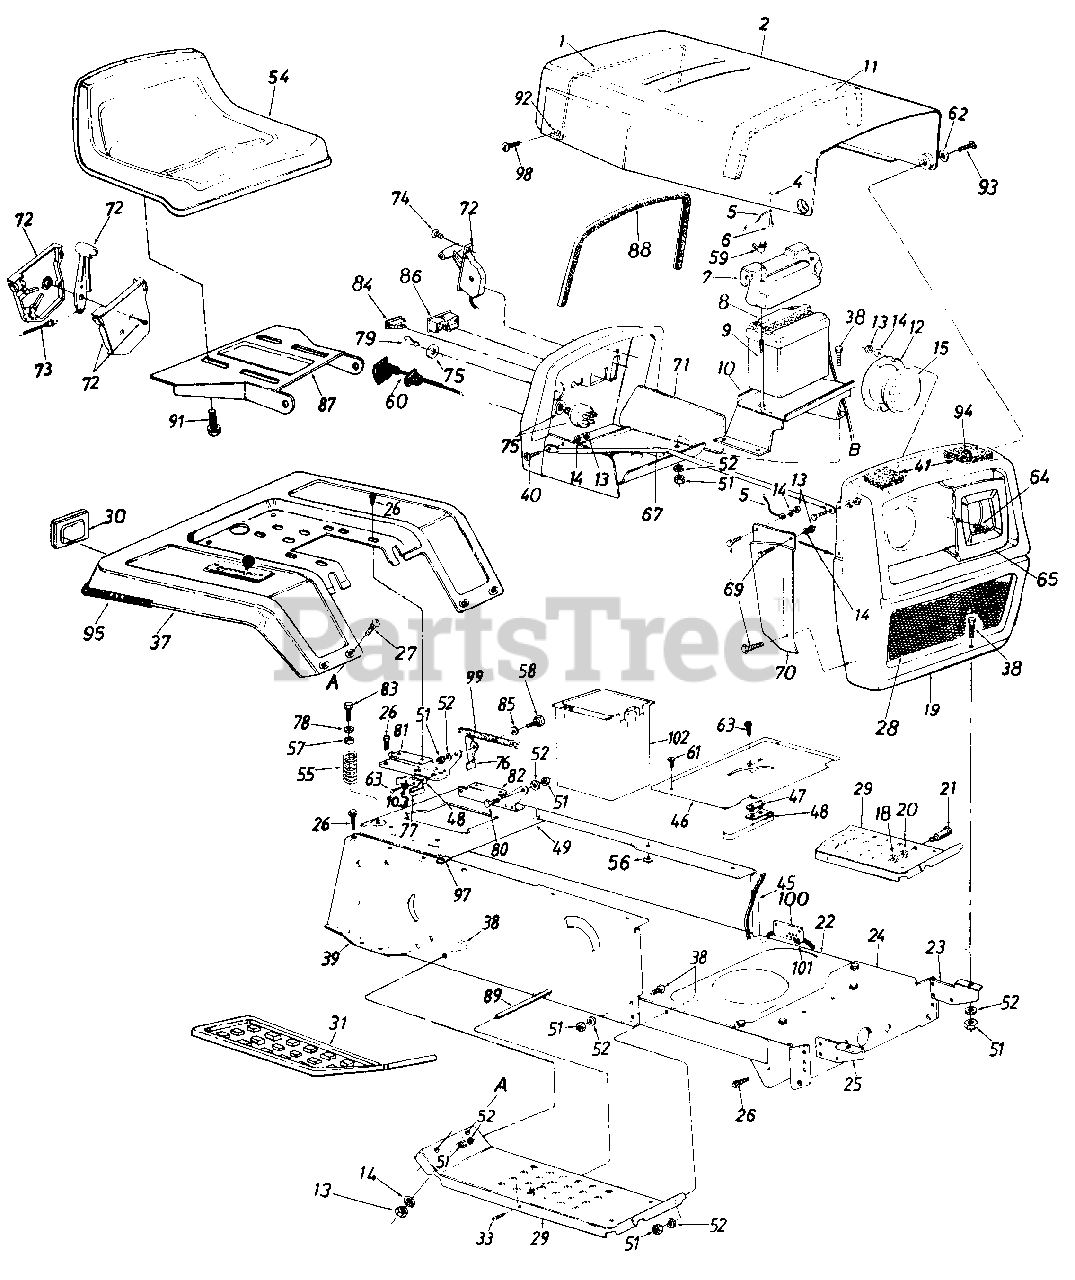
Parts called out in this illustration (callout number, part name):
5	Hood Stop 7" Lg.
6	Pop Rivet
7	Battery Cover
8	12 Volt Battery
9	Battery Hold Down Rod
10	Battery Bracket
11	PVC Foam-Strip
12	Headlight Retainer
13	Hex Nut 1/4-20 Thd.
14	L-Wash. 1/4" I.D.
15	Headlight
18	Hex Nut 3/8-16 Thd.
19	Grille Ass'y.
20	L-Wash. 3/8" I.D.
21	Shld. Bolt .50" Dia. x .84
22	Lower Frame
23	Grille Mount Brkt.
24	Front Pivot Brkt.
25	Grille Mount Brkt.
26	Hex Wash. Hd. AB-Tap Scr. 5/16 x .75" Lg.
27	Carriage Bolt 1/4-20 x .5" Lg.
28	Grille Insert
29	Running Board
30	Reflector
31	Foot Pad-L.H.
33	Truss Mach. Scr. 5/16-18 x .75" Lg.
37	Fender
38	Hex Bolt 5/16-18 x .75" Lg.
39	R.H. Side Frame
40	Hex Bolt 1/4-20 x .62" Lg.
45	L.H. Side Frame
46	Shift Cover
47	Reverse Safety Switch
48	Insulator Nut Plate
49	Hitch Plate
51	Hex Nut 5/16-18 Thd.
52	L-Wash. 5/16" I.D.
54	Seat Ass'y.
55	Compression Spring
56	Ext. L-Wash. 5/16" I.D.
58	Shld. Bolt.437" Dia. x .268"
59	Wing Nut 1/4-20 Thd.-Plastic
60	Choke Control 46" Lg.
61	Truss Mach. Tap Scr. #10 x .50" Lg.
62	Washer .39" l.D. x .62" O.D.
63	Hex Wash. Hd. AB-Tap Scr. #8 x .50
64	Oval C 0 Sunk Mach. Scr. 1/4-20 x 1.5" Lg.
69	Truss Hd. Scr. 1/4-20 x .75 Lg.
70	R.H.-Grille Side Panel
73	Throttle Control Wire-35"
74	Truss Mach. A8-Tap Scr. #10 x .5" Lg.
75	Ignition Switch
76	Seat Lift Bracket
77	Spring Switch
78	Fl-Wash. .344" l.D.
79	Ignition Key
80	Shld. Bolt .437" Dia. x .162"
81	Seat Pivot Brkt. Support-R.H.
82	Seat Pivot Brkt. Support-L.H.
83	Hex Hd. Tap Scr. 5/16-18 x l" Lg.
84	Light Switch
85	Spr-Wash. .445" I.D. x .75" O.D.
86	Ammeter
87	Seat Pivot Bracket
88	Molding Strip 27" Lg.
89	Running Board Rod
91	Hex Wash. Hd. Tap Scr. 3/8-16 x .75" Lg.
92	Hood Spring Retainer
93	Shld. Bolt .375 Dia. x .125
94	L-Nut 1/4-28 Thd.
95	Trim Strip 31.0" Lg.
97	Speed Nut #10Z
98	Self-Tap Scr. .5" Lg.
99	Extension Spring 5.31 Lg.
100	Brake Cable Bracket
103	Fiber Washer
